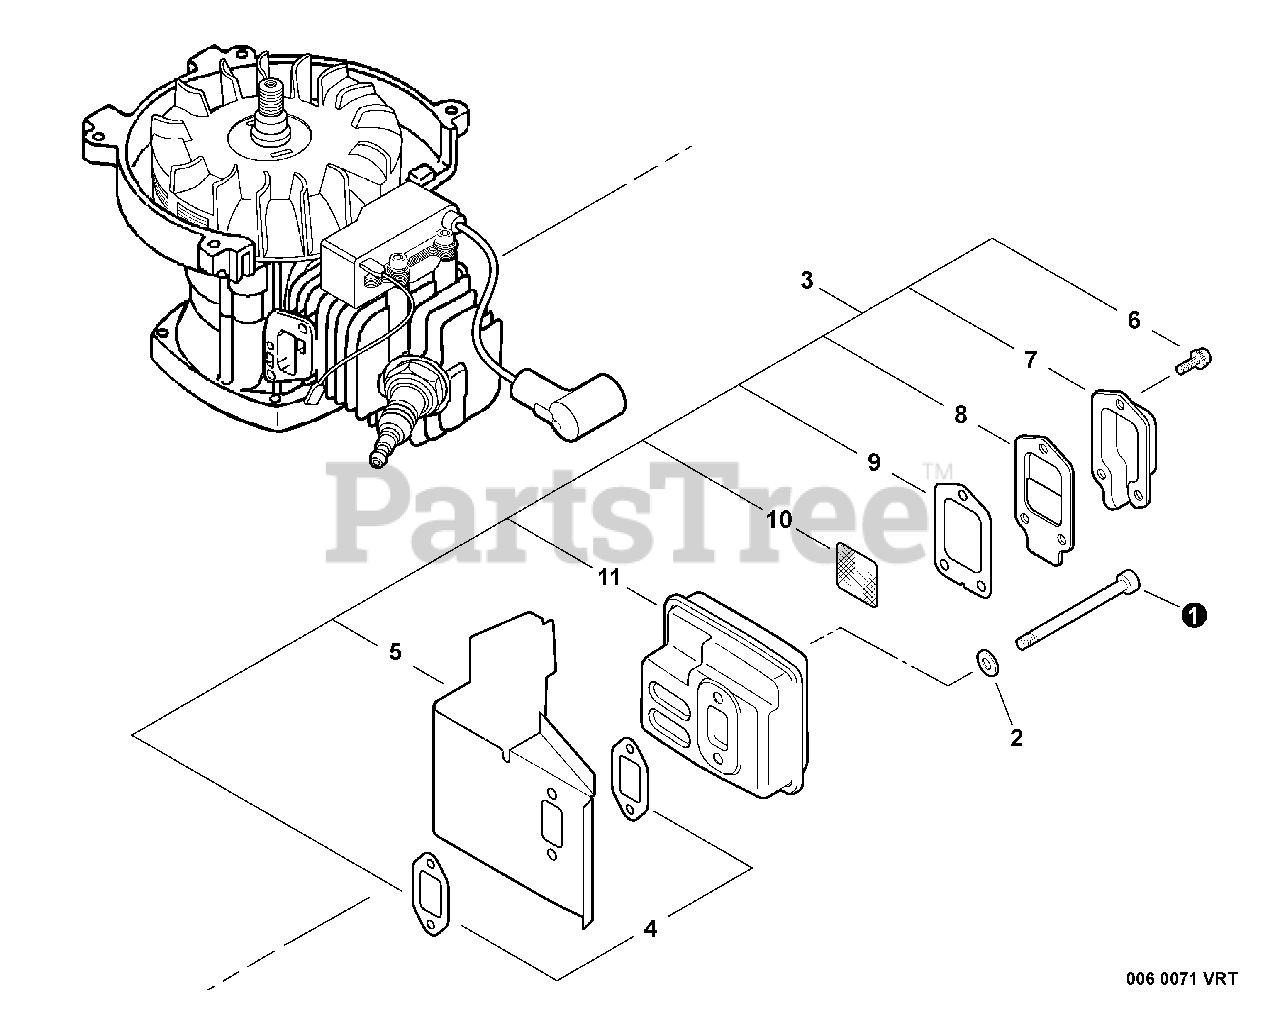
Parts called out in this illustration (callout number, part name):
1	SCREW - 5X50
2	WASHER - 5
3	MUFFLER ASSY
4	GASKET, EXHAUST
5	SHIELD, EXHAUST
6	SCREW - 4X10
7	GUIDE, EXHAUST - OUTER
8	GASKET, EXHAUST - INNER
9	GASKET, EXHAUST
10	SCREEN, SPARK ARRESTOR
